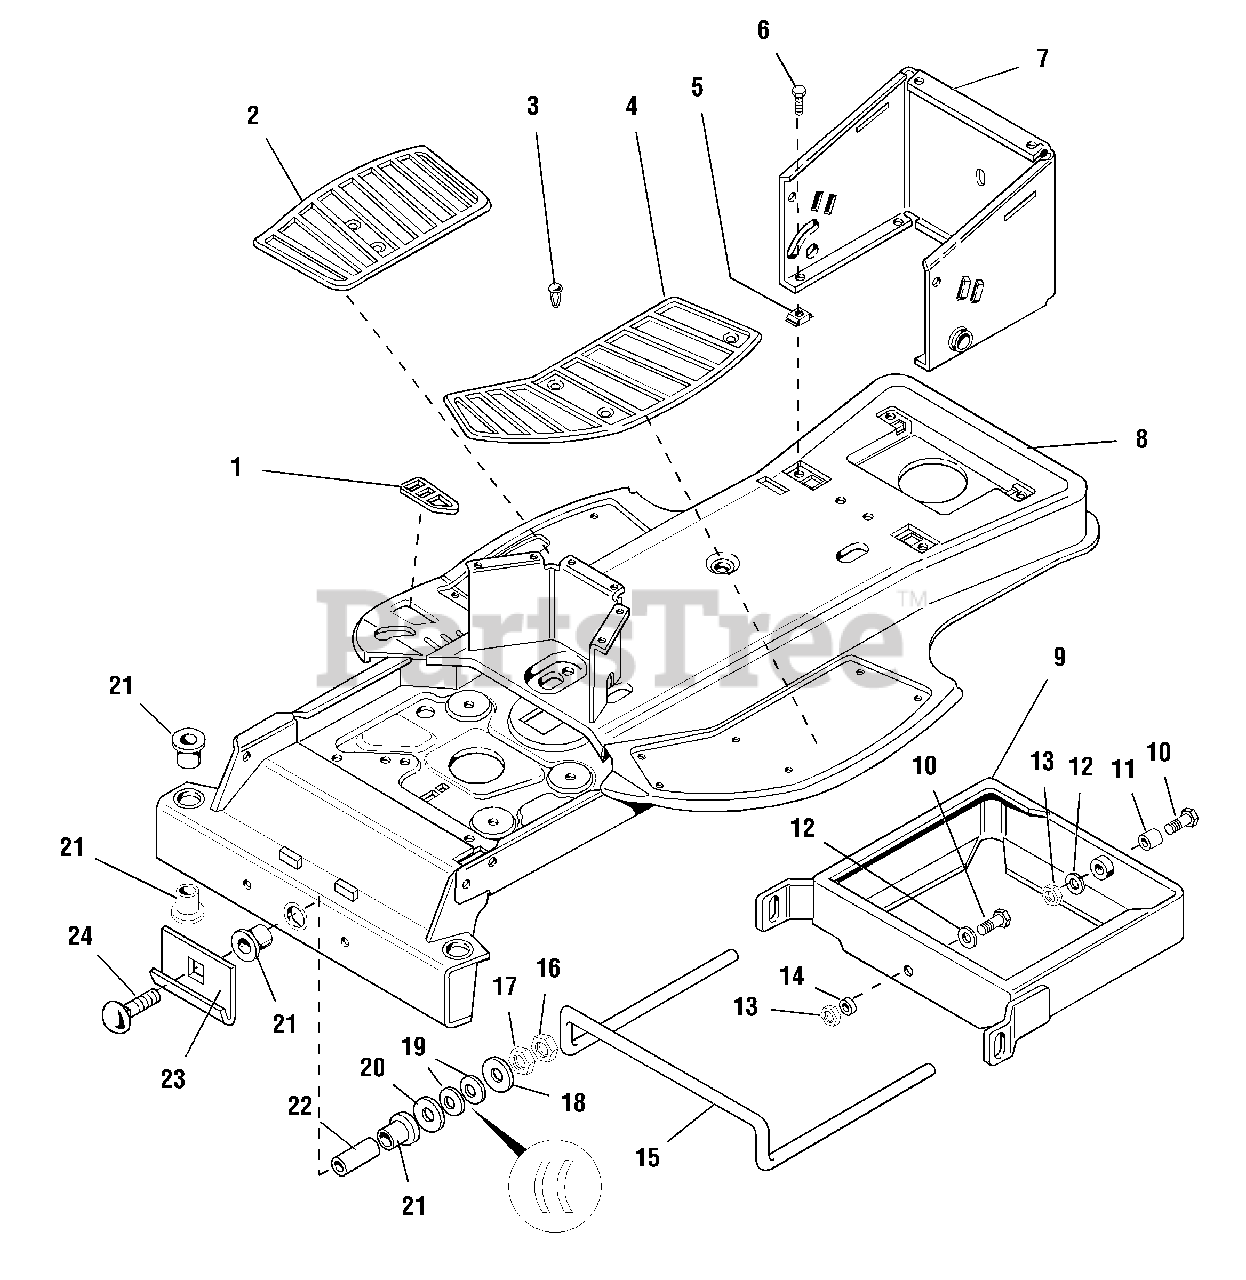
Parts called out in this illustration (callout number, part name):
1	PLUG, Hole
2	PAD, Footrest, RH
3	FASTENER, Panel
4	PAD, Footrest, LH
5	NUT, Tinn, 5/16-18
6	SCREW, Whiz, 5/16-18 x 3/4
7	WRAPPER, Rear Frame
8	FRAME ASSEMBLY
9	CARRIER ASSEMBLY
10	CAPSCREW, 3/8-16 x 1-1/4
12	WASHER, 3/8
13	NUT, Flange Lock, 3/8-16
15	TORSION BAR
16	NUT, Hex, 5/16-18
17	NUT, Hex, Nylon Lock, 5/16-18
18	WASHER, Large
19	WASHER, Spring
20	WASHER, 3/4 x 1-1/4 x 1/2
24	CARRIAGE BOLT, 5/16-18 x 3-1/4
